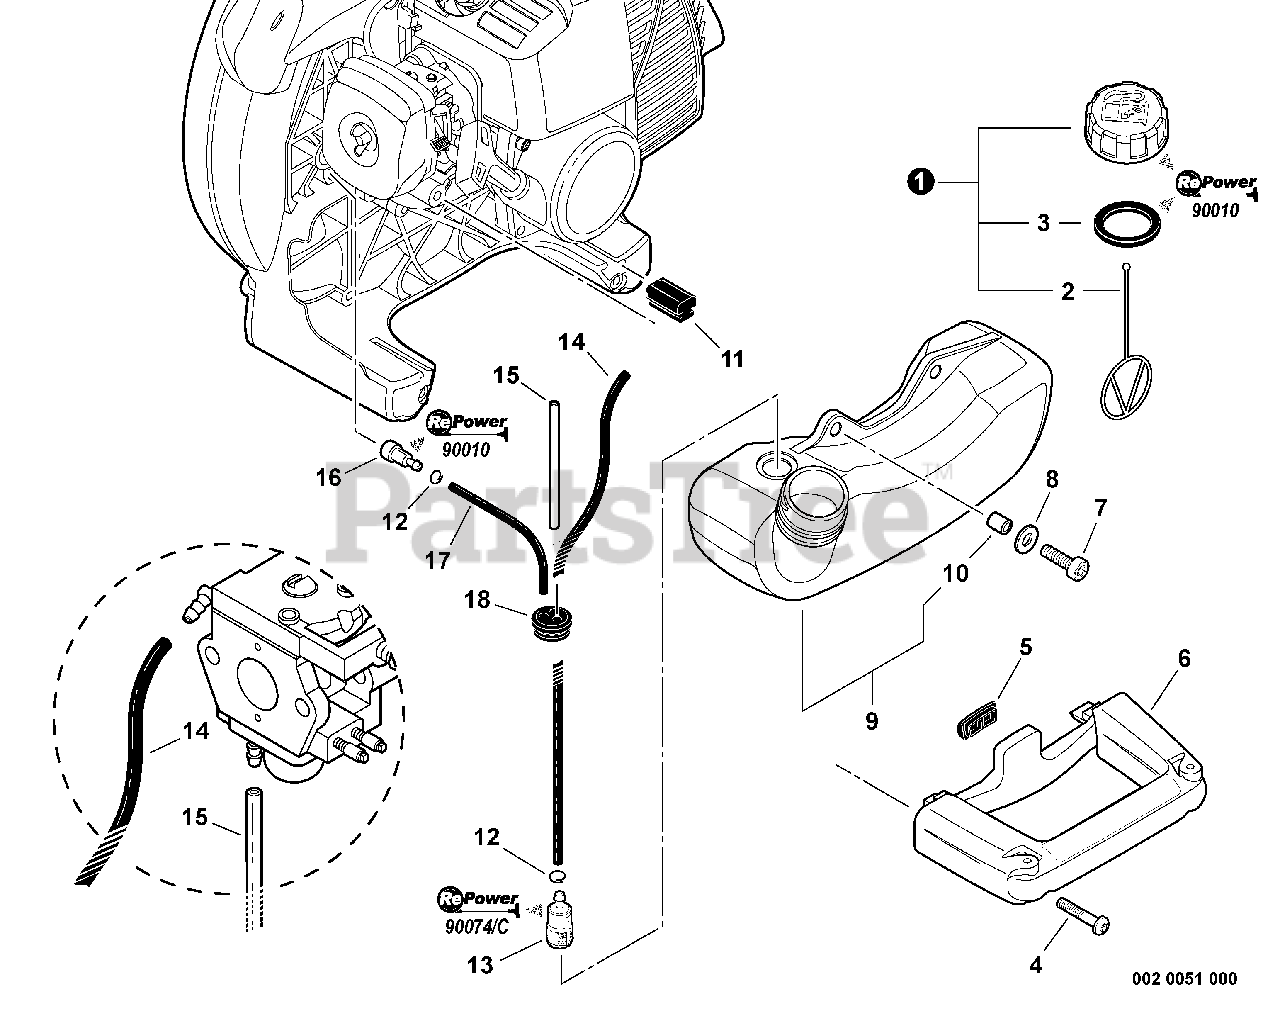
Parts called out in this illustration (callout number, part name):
1	CAP ASSY - ORANGE
2	CONNECTOR, CAP
3	GASKET, CAP
4	SCREW - 5X25
5	CUSHION
6	HANDLE - SIDE
7	SCREW - 5X16
8	WASHER - 5
9	FUEL TANK ASSY
12	CLIP - 6
13	FILTER, FUEL
14	PIPE - 3X5X210 -- BLACK
15	PIPE - 3X6X85 -- CLEAR
16	VENT, FUEL TANK
17	PIPE - 3X6X80 -- BLACK
18	GROMMET
19	RePower TUNE-UP KIT
20	Repower CAP AND VENT KIT
